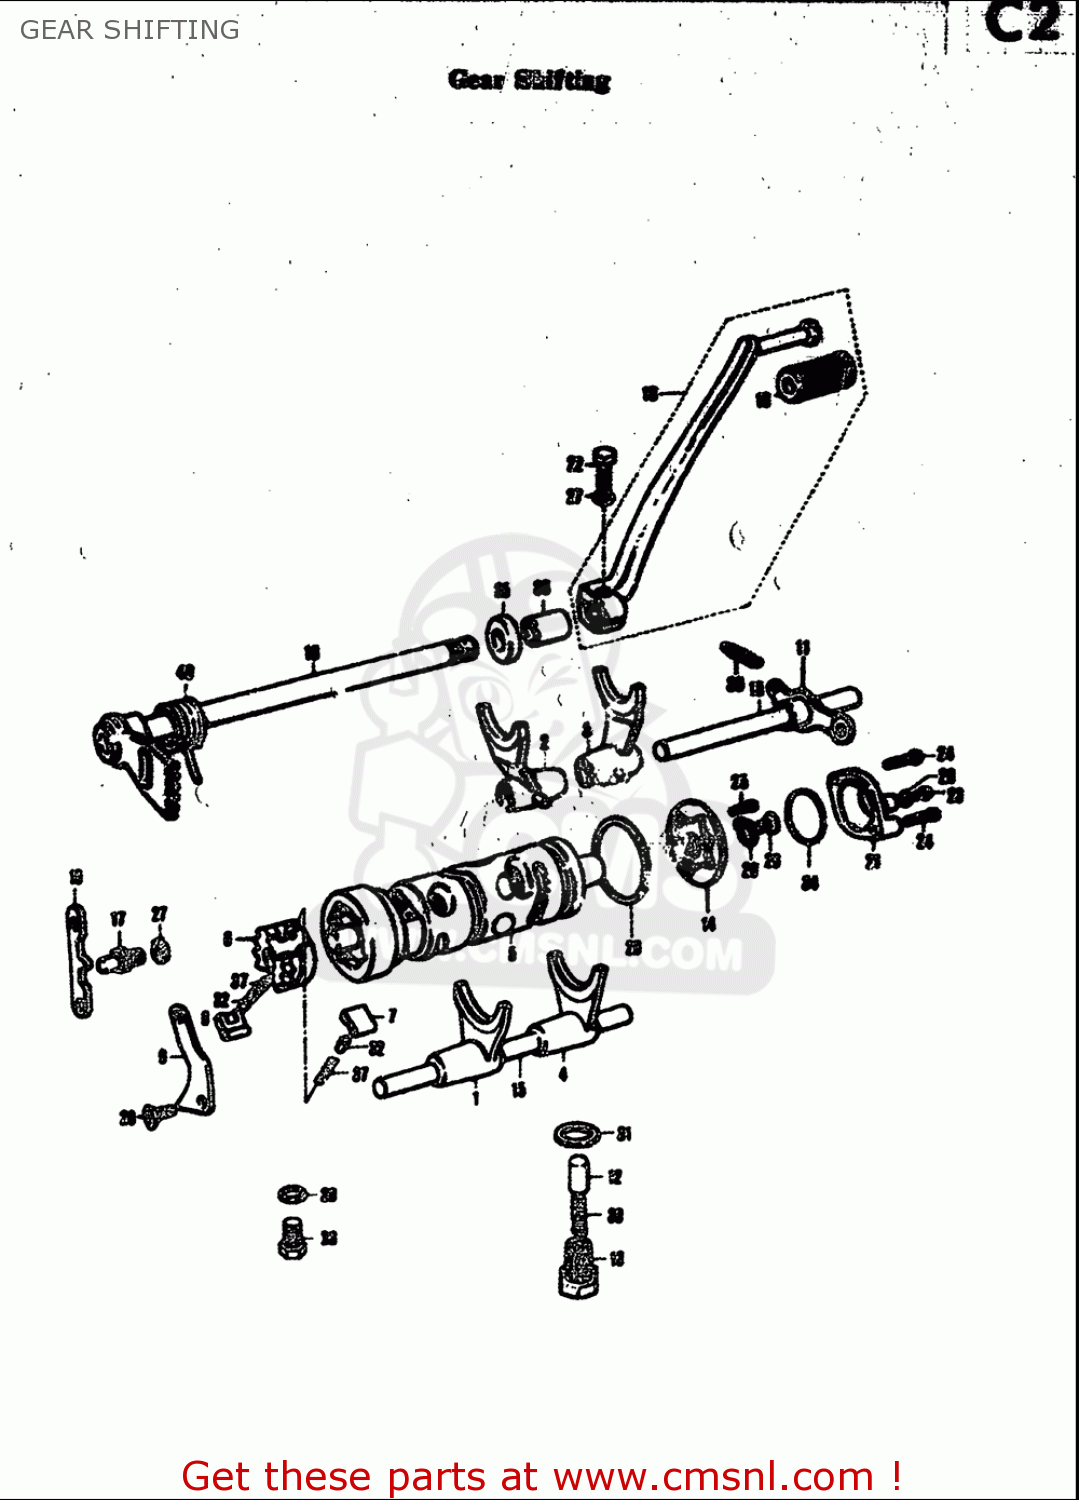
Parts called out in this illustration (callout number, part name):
6	GEAR,GEAR SHIFT CAM DRIVEN
7	PAWL,GEAR SHIFT NO.1
8	PAWL,GEAR SHIFT NO.2
9	LIFTER,GEAR SHIFT PAWL
10	GUIDE,GEAR SHIFT CAM
13	HOUSING,GEAR SHIFT CAM STOPPER
17	STOPPER,GEAR SHIFT ARM
18	LEVER ASSEMBLY,GEAR SHIFTING
19	RUBBER,GEAR SHIFT PEDAL
20	CONTACT,GEAR SHIFT SWITCH
21	BODY,GEAR SHIFT SWITCH
22	BOLT
23	SCREW
27	WASHER,LOCK
28	WASHER
29	WASHER(40X45X1)
30	GASKET(10X14X3.6) (NAS)
31	GASKET(14X19.2X2) (NAS)
32	PIN(5X8)
33	PLUG
34	GASKET (MCA)
35	SEAL,OIL (12X22X9)
36	CUSHION
37	SPRING
38	SPRING
40	SPRING
